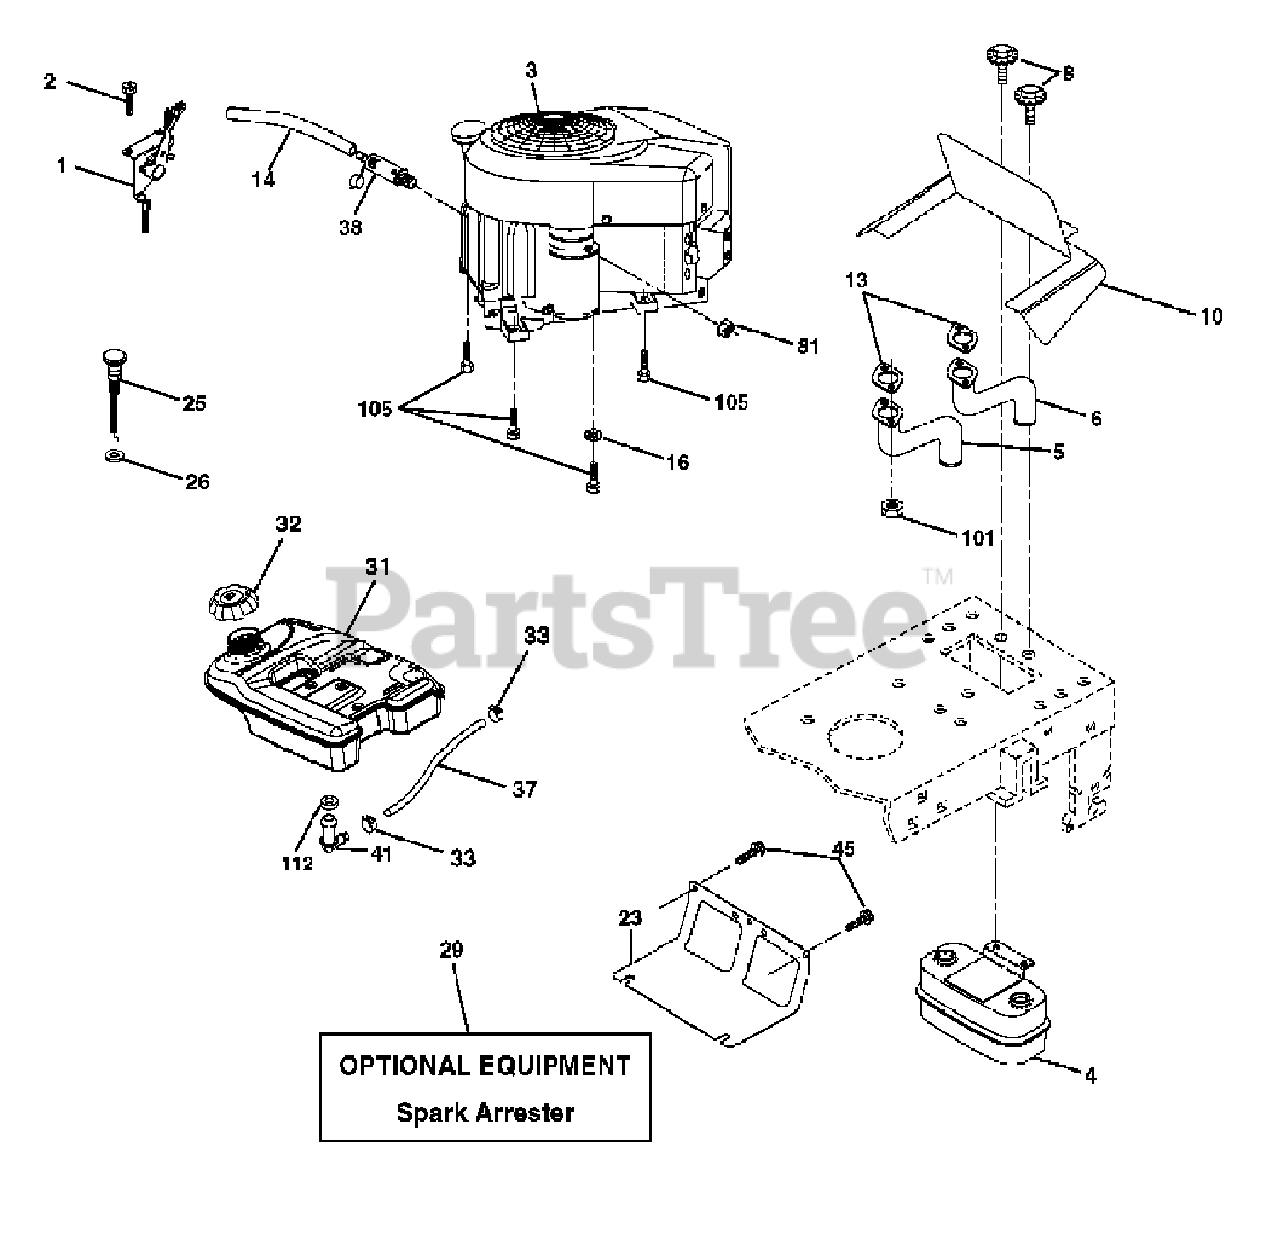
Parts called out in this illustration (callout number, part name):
1	Control Throt Flg
2	Screw Hex Thd Cut 1/4-20x5/8 T
4	Muffler Asm Twin Lo-Tone
5	Exhaust Tube Lh
6	Exhaust Tube Rh
8	Bolt 5/16-18unc x 3/4 W/Sems
10	Shield Browning
13	Gasket Muffler
14	Tube Drain Oil Easy
16	Washer Lock Ext Tooth 3/8
23	Shield Browning
25	Choke Control
26	Nut, Keps 3/8-24 Unf
29	Kit Spark Arrestor (Flat Scrn)
31	Tank Fuel 4.0 Rear
32	Cap Asm Fuel Gauge
33	Clamp Hose Blk
37	Line Fuel
38	Plug Drain Oil
41	Stem Tank Fuel
45	Screw Hexwsh Thdr 3/8-16 x 3/4
81	Nut Keps Hex 1/4-20
101	Nut Flange M8-1.25
105	Screw 3/8-16 x 1
112	Bushing
